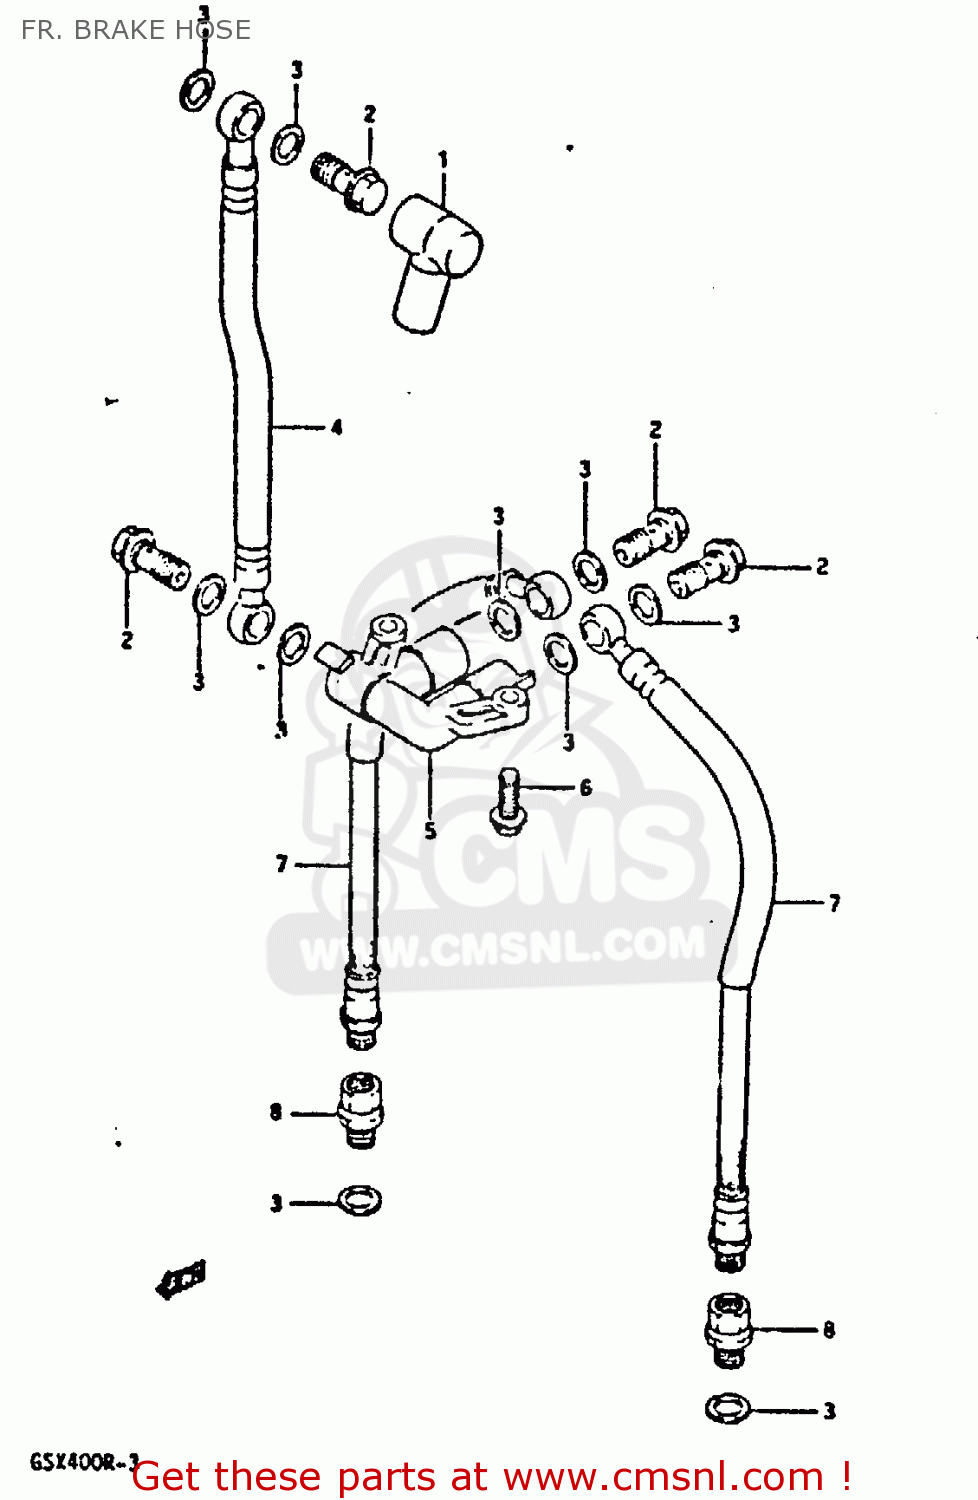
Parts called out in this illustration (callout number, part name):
1	BOOT
2	BOLT UNION
3	WASHER(10X15X1.5)
5	BRAKE HOSE JOIN
6	BOLT,REAR
8	ADAPTER,BRAKE HOSE
